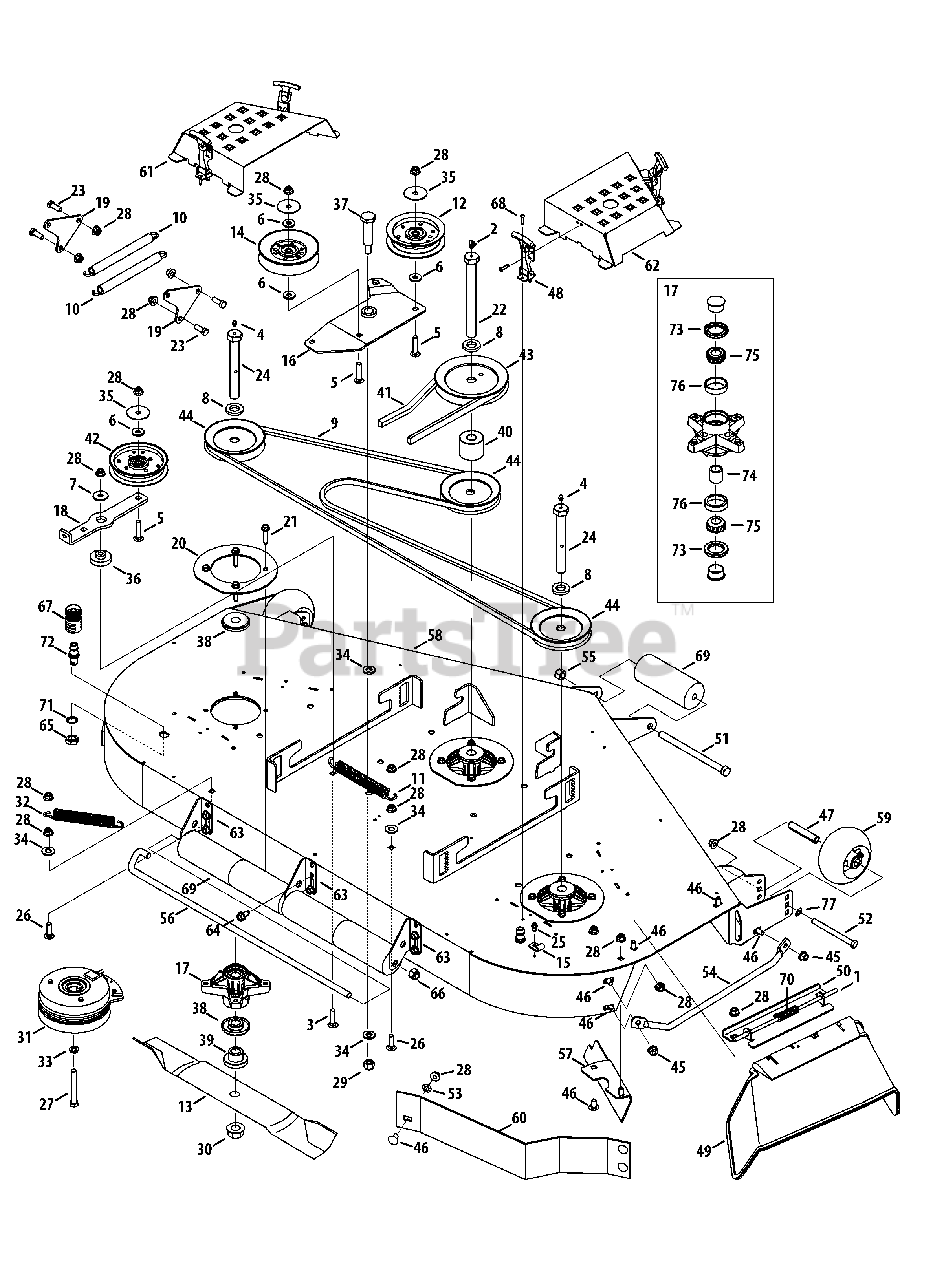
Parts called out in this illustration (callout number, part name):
1	Chute Deflector Rod
2	Grease Fitting, 1/4-28 x .788
3	Carriage Bolt, 3/8-16 x 1.50
4	Straight Grease Fitting, 1/4-28
5	Carriage Bolt, 3/8-18 x 1.75
6	Washer, .406 x 1.00 x .105
7	Washer, .411 x 1.25 x 1.00
8	Spacer, .812 x 1.47 x .218
9	V- Belt
10	Hook Ext. Spring, .75 x 7.89 x .14
11	Hook Ext. Spring, .94 x 7.57 x .14
12	Idler Pulley, 4.88
13	Hi-Lift Blade, 21.0
14	Idler Pulley, 5.06
15	Retainer Hook Bracket
17	Deck Spindle Assembly
18	Deck Idler Arm
19	Spring Mount Plate
20	Spindle Reinforcement Plate
21	Screw TT, 5/16-18 x 1.50
22	Hex Screw, 3/4-16 x 8.0
23	Hex Screw, 3/8-16 x 1.00
24	Hex Screw, 3/4-16 x 6.00
25	Hex Washer TT Screw, 1/4-20 x .500
26	Carriage Bolt, 3/8-16 x 1.25
27	Hex Screw, 7/16-20 x 3.25
28	Flange Lock Nut, 3/8-16
29	Hex Lock Nut, 1/2-20
30	Flange Lock Nut, 3/4-16
31	Electric PTO Clutch
32	Extension Spring, .91 x 7.33
33	Lock Washer, 7/16
34	Washer, .510 x 1.00 x .125
35	Flat Washer, .406 x 1.92 x .060
36	Shoulder Spacer, .854 x .280
37	Shoulder Bolt, .74 Dia. x 2.47
38	Deck Spindle Spacer
39	Spindle Spacer, .76 x 2.00 x 1.1
40	Spacer, .76 x 2.0 x 1.1
42	Idler Pulley, 4.25
43	V-Type Pulley
44	V-Type Pulley
45	Counterlock Flange Nut, 3/8-16
46	Carriage Bolt, 3/8-16 x .75
47	Spacer, .390 x .620 x 3.04
48	T-Handle Latch Draw
49	Fab Deck Deflector Chute
50	Deflector Chute Bracket
51	Hex Screw, 1/2-20 x 7.50
52	Hex Screw, 3/8-16 x 4.00
53	Push Retainer Nut
54	Fab Deck Chute Finger Guard
55	Nylock Nut, 1/2-20
56	J-Hook w/ Threaded Roller
57	Deck Chute Baffle
58	60" Deck
59	Deck Wheel
60	Standard Baffle
61	60" LH Belt Cover
62	60" RH Belt Cover
63	Roller Mount Bracket
64	Screw TT, 3/8-16 x .75
65	Hex Nut, M16-1.5
66	Lock Nut, Nylon Insert, 1/2-13
67	Water Nozzle Adapter
68	Pop Rivet, .187 Dia.
69	Front Roller
70	Spring Torsion, 0.639 ID x 2.16 LG
71	Lock Washer, 17 x 23.8 x 1.95
72	Water Deck Nozzle
74	Spacer, .78 x 1.0
75	Cone Bearing
76	Cup Bearing
77	Thrust Washer, .375 x .70 x .030
